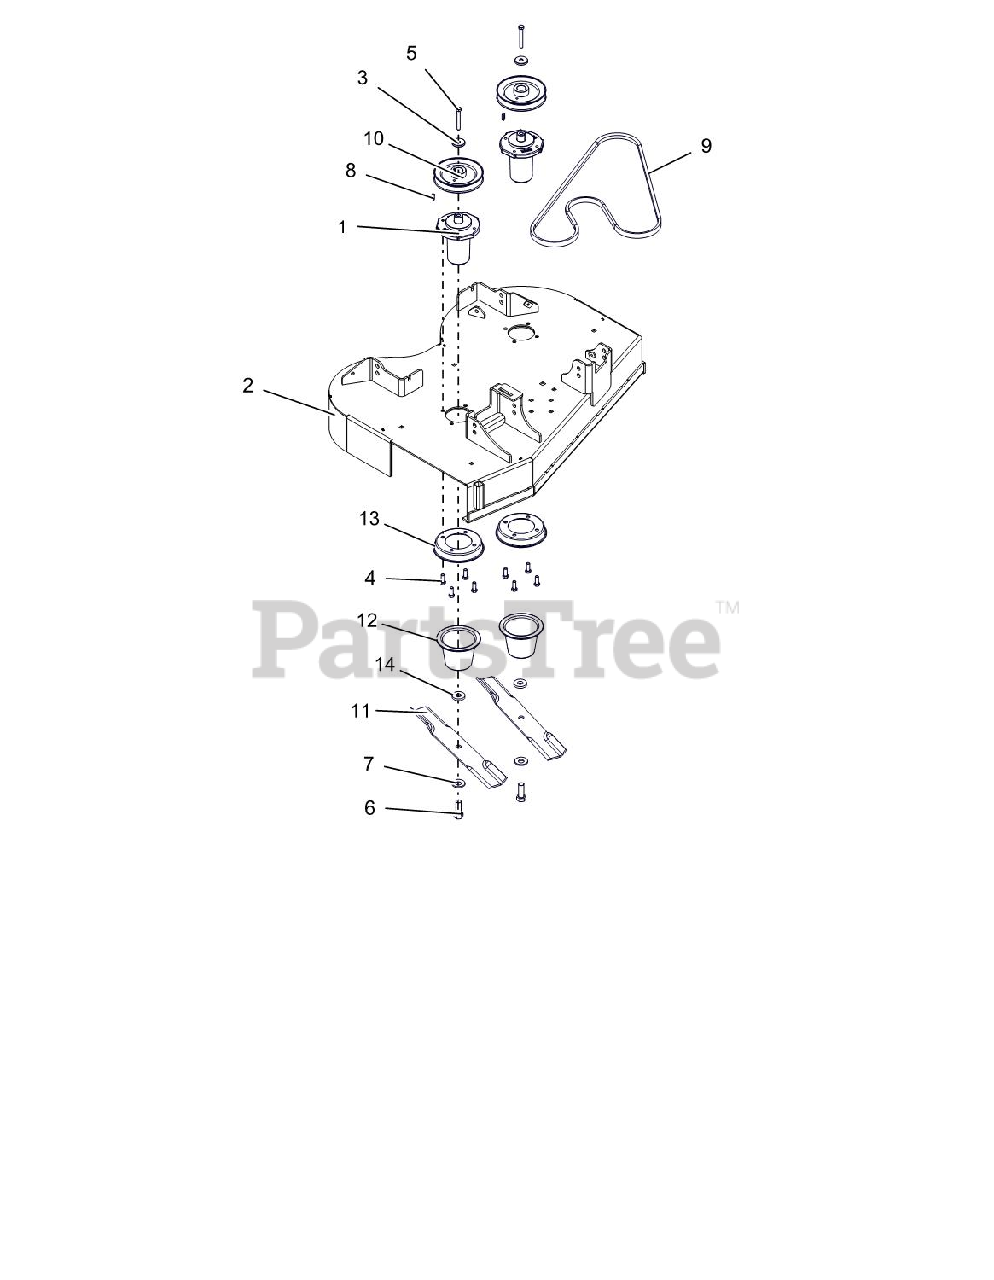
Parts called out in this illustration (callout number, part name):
1	ASM, MAINT FREE SPINDLE-SHORT
2	ASM, 36" DECK W/DECALS
3	RETAINER, SHEAVE
4	BLT-HEX .38-16X1.0 GR8 YZ EP30
5	BLT-HEX .38-16X2.75 GR8 YWZC
6	BLT-HEX .62-18X1.75 GR8 YWZC
7	WSHR-BLVL .669X1.535X.138
8	KEY-STR .25X.75X.25
9	BELT, 5L
10	PULLEY, V-1"ID X 5.75" OD
11	BLADE, 18.000 X .80 LIFT
12	GUARD, SPINDLE LOWER
13	GUARD, SPINDLE TOP
14	WSHR-FL-STL .630X1.50X.25 YWZC
